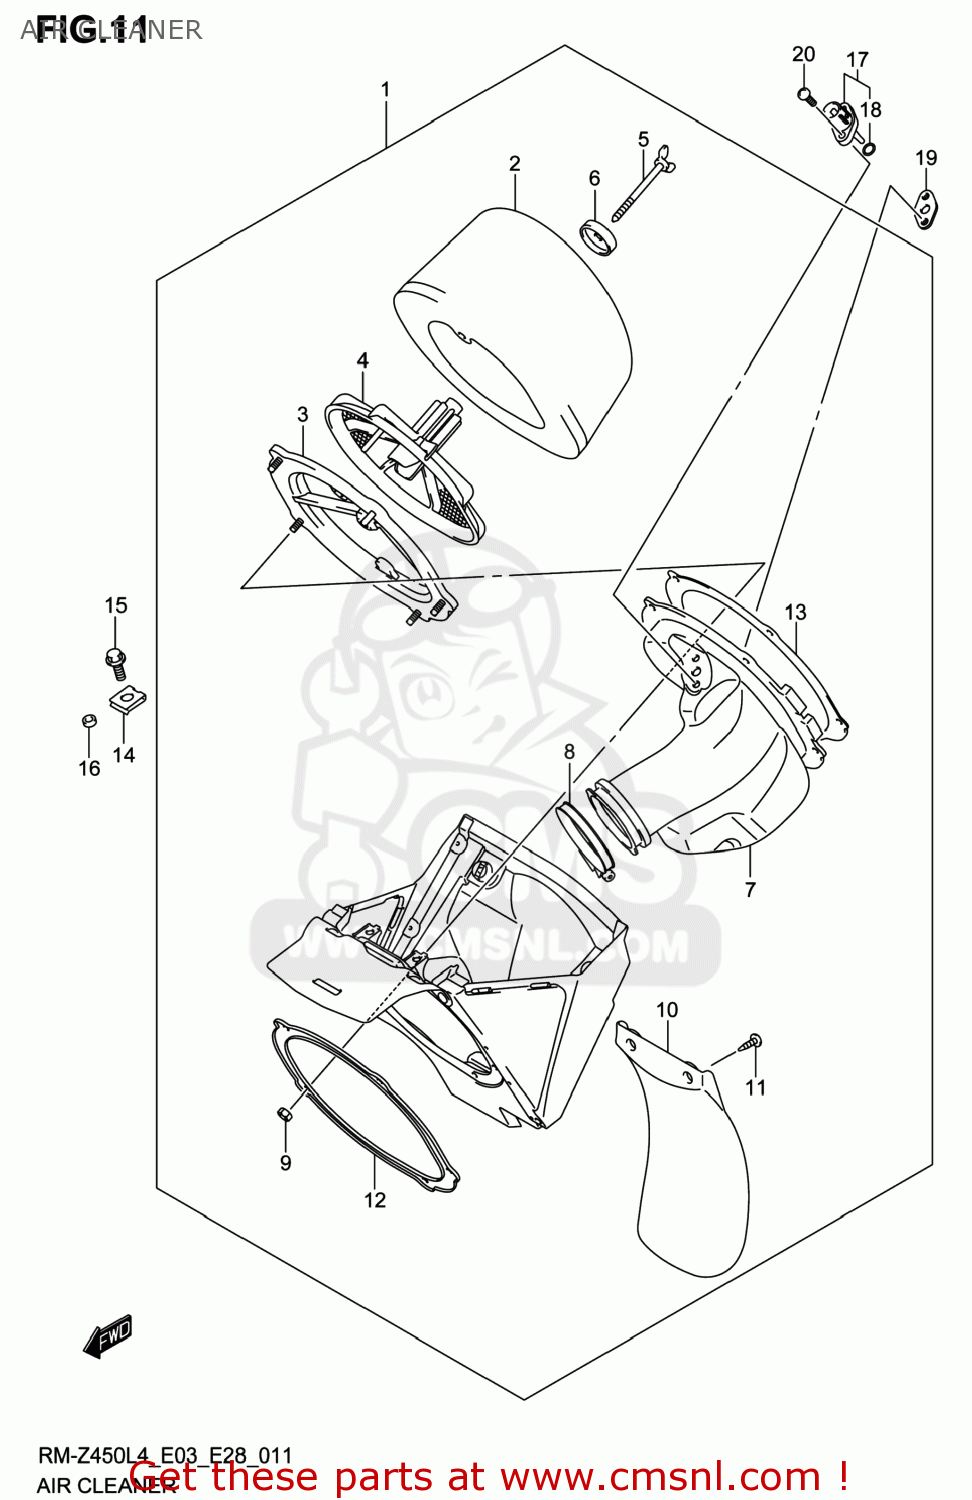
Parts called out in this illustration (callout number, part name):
1	CLEANER ASSY,AIR
2	FILTER ASSY
3	BASE,FILTER
4	HOLDER,FILTER
5	BOLT,WING
6	WASHER,AIR CLEANER
7	TUBE,OUTLET
8	CLAMP,THROTTLE BODY SIDE
9	NUT
10	MUDGUARD
11	SCREW
12	PLATE
13	GASKET (NAS)
14	NUT
15	BOLT
16	SPACER(6.2X10X2.2)
17	SENSOR,AIR TEMP
18	O RING
19	BRACKET,AIR TEMP SENSOR
20	SCREW
